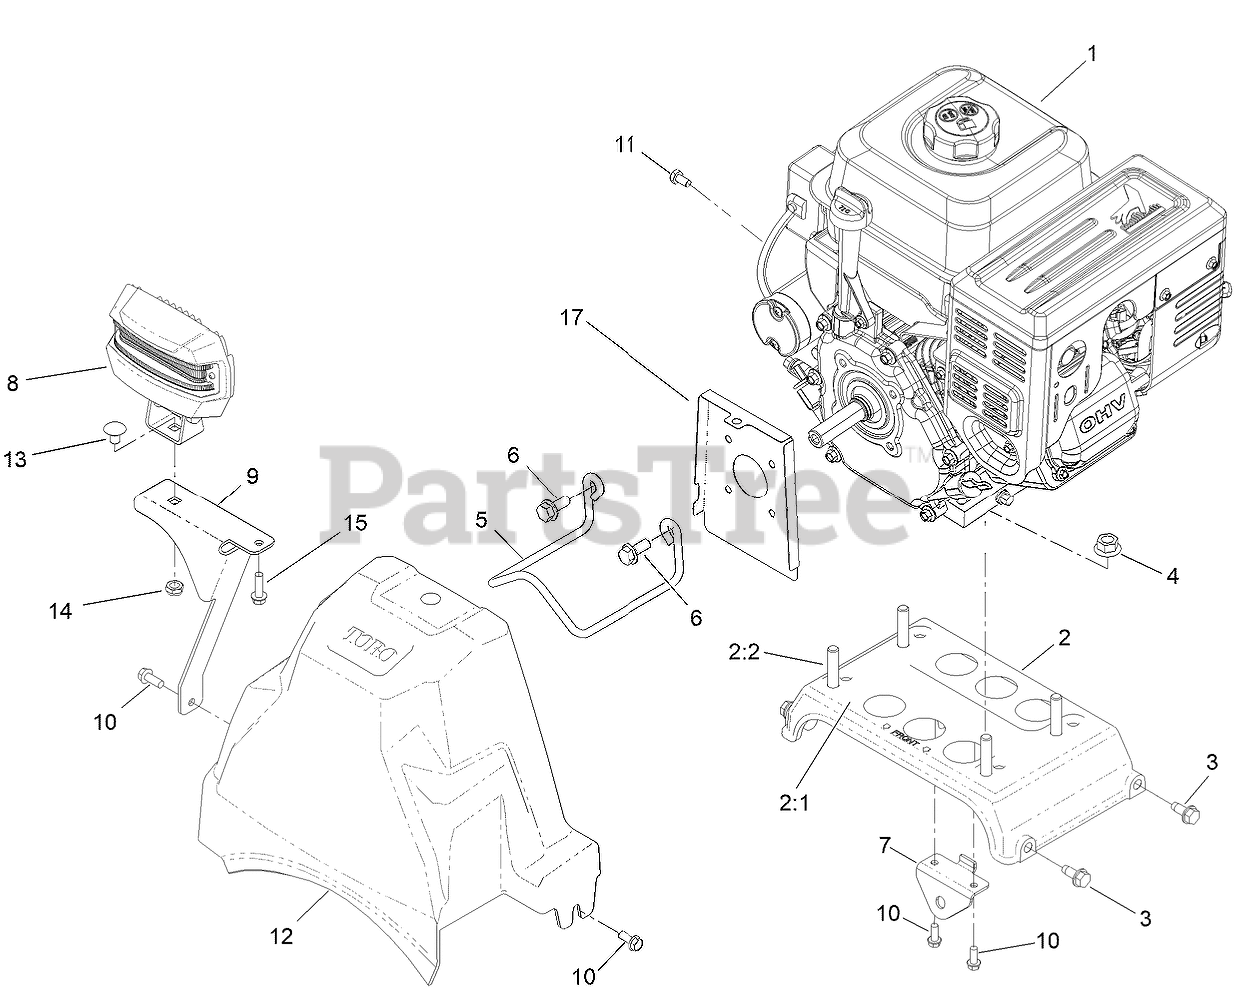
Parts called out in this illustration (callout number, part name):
1	ENGINE-G250FDS-1
2	ENGINE PLATE ASM (G250)
2:1	PLATE-ENGINE
2:2	STUD-PRESS 95/16-18 X 1.625)
3	SCREW-HWHTF
4	NUT-HF
5	GUIDE-BELT
6	SCREW-HH
7	BRACKET-CONTROL, TRACTION
8	LED LIGHT ASM
9	BRACKET-LIGHT
10	SCREW-HWH
11	SCREW-HH
12	COVER-BELT
13	BOLT-CARR
14	NUT-HEX
15	SCREW-PLASTITE, HWH
17	COVER-CRANK
